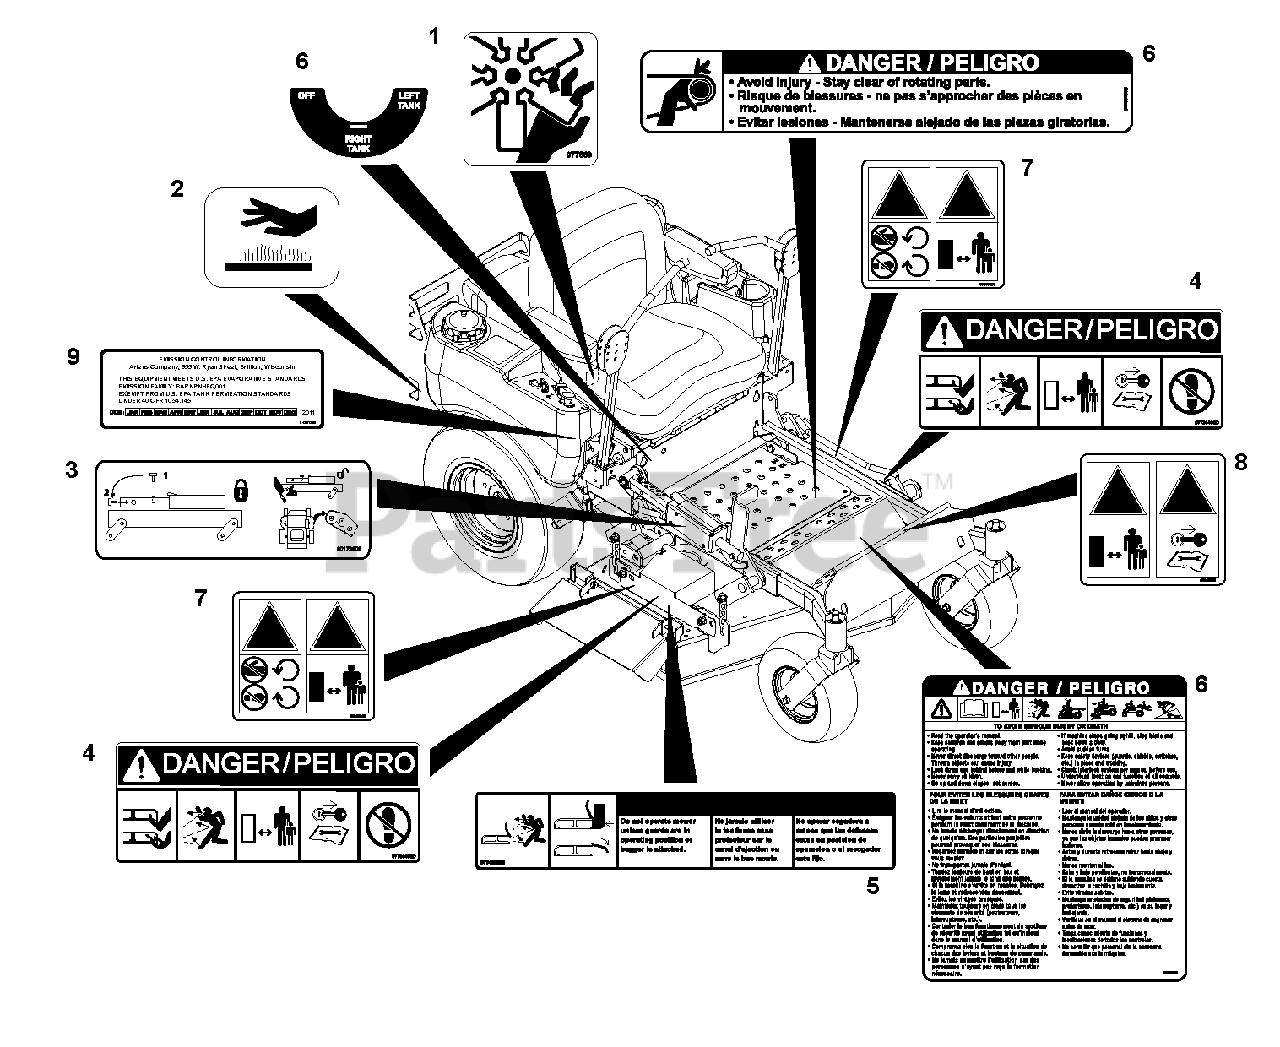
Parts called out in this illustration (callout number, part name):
1	Decal, Danger Fan
2	Decal, Hot Surface
3	Decal, Deck Service
4	Decal, Mower Pan Head Danger
5	Decal, Warning
6	Set, Decal Common Danger/Fuel
7	Decal, CE Deck
8	Decal, CE Caution
9	Label, EPA Non-Compliant Tank
